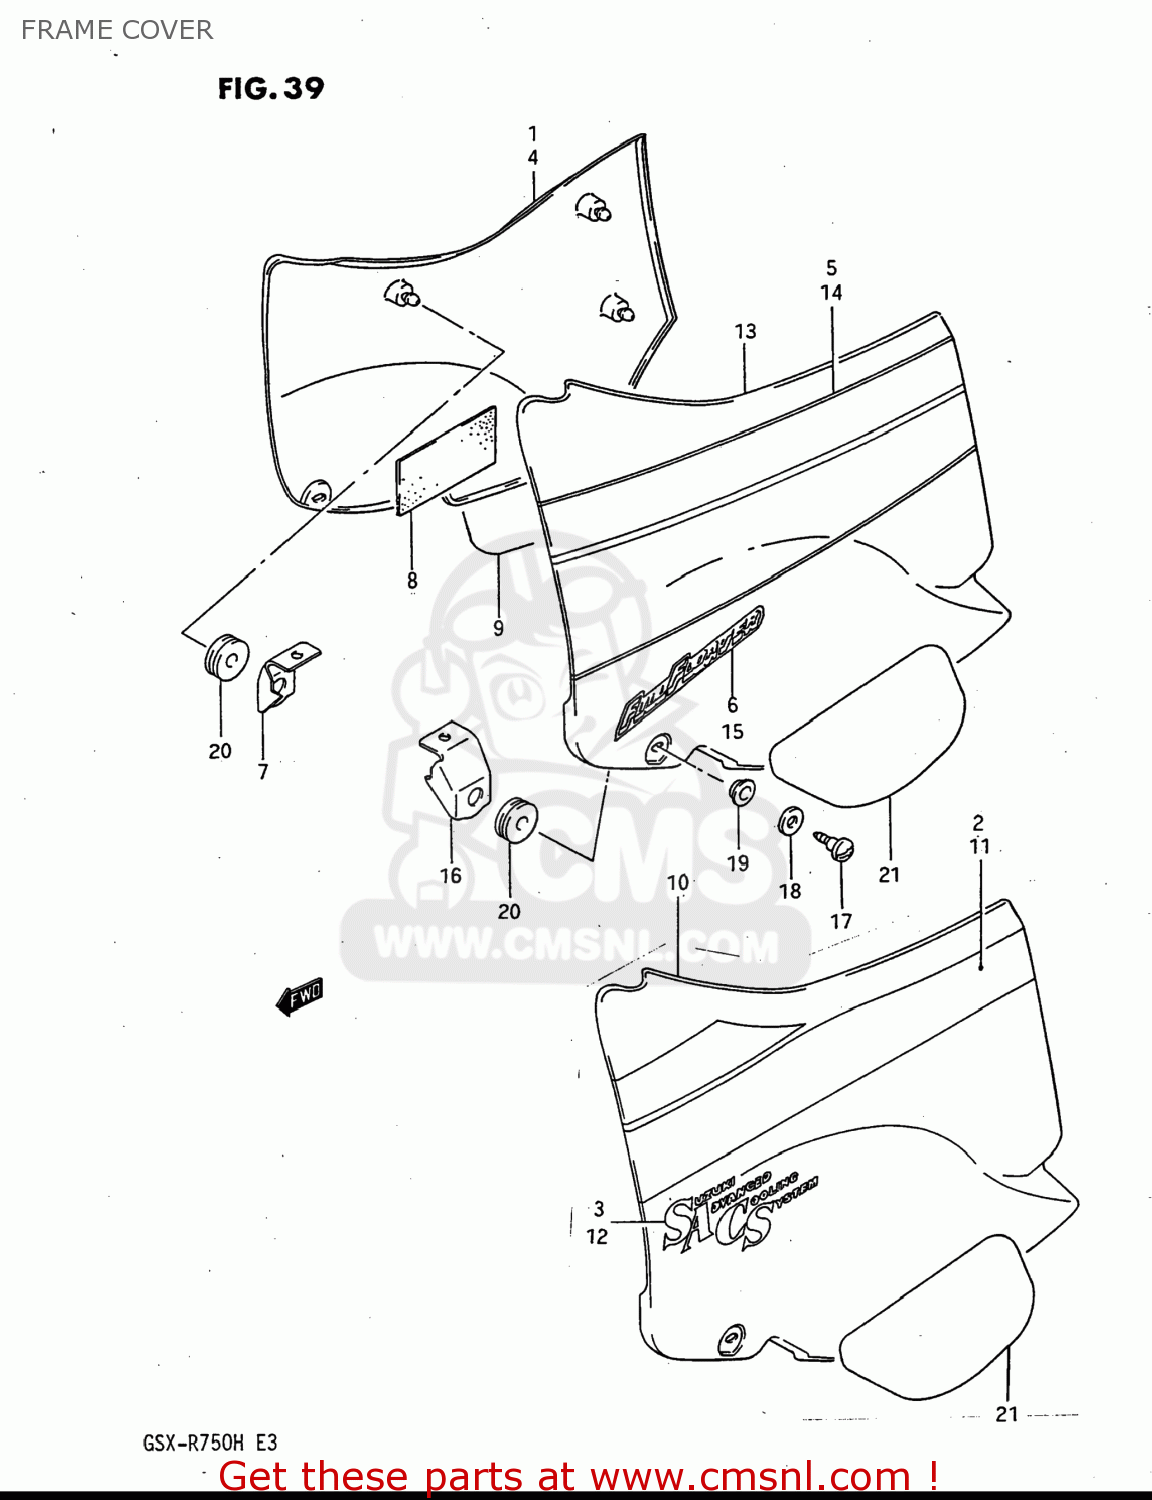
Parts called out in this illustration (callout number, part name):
1	COVER,FRAME,RIGHT
2	TAPE SET,FRAME COVER
3	EMBLEM
4	COVER,FRAME,RIGHT
5	TAPE SET,FRAME COVER,RIGHT
6	EMBLEM
7	HOLDER,FRAME COVER,RIGHT
8	RUBBER,FRAME COVER,RIGHT
9	PROTECTOR,FRAME COVER
10	COVER,FRAME,LEFT
11	TAPE SET,FRAME COVER,LEFT
12	EMBLEM
13	COVER,FRAME,LEFT
14	TAPE SET,FRAME COVER,LEFT
15	EMBLEM
16	HOLDER,FRAME COVER,LEFT
17	SCREW(6X23)
18	WASHER
19	CUSHION
20	CUSHION
21	PROTECTOR,FRAME COVER LH
